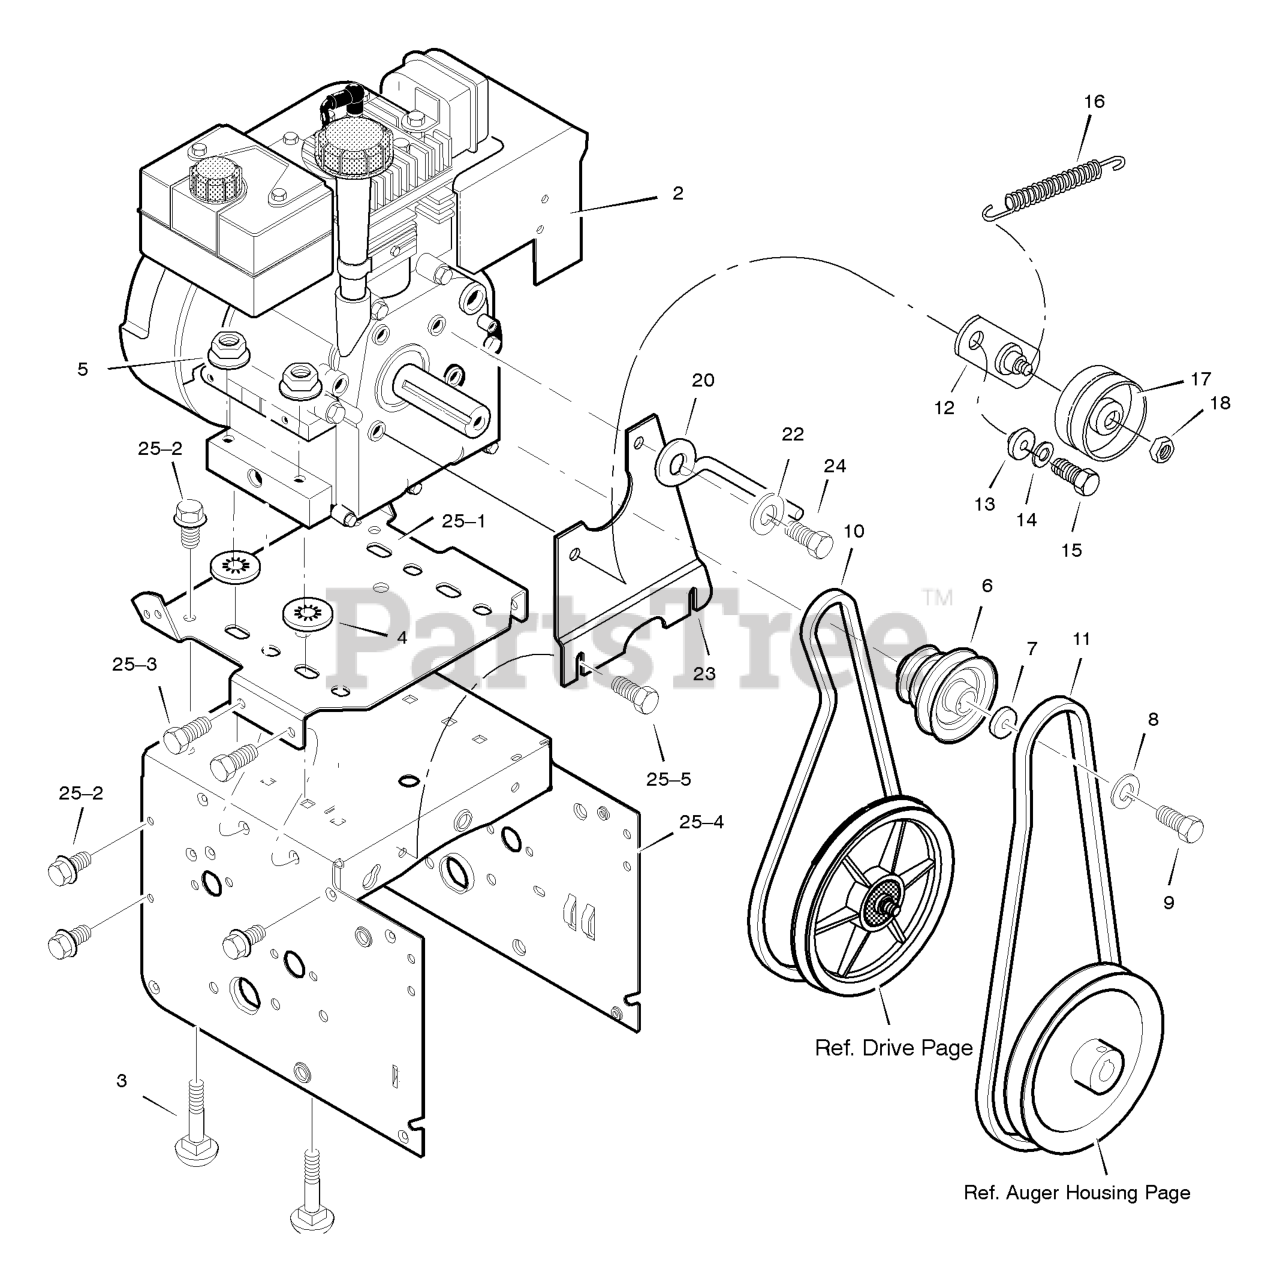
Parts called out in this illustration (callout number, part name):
2	ENGINE
3	BOLT, CARRIAGE 5/16-18
4	RETAINER, PUSH
5	NUT, HEX 5/16-18
6	PULLEY, ENGINE
7	WASHER
8	WASHER .38ID
9	SCREW, 3/8-24 x 1.00
10	BELT, DRIVE V 3L
11	BELT, AUGER V 4L
12	BRACKET ASSEMBLY, IDLER
13	BUSHING, IDLER BRACKET
14	WASHER, SPLIT
15	SCREW 5/16-24 X 1.00
16	SPRING, IDLER TRACTION DRIVE
17	PULLEY, IDLER
18	NUT, JAM 3/8-16
20	GUIDE, BELT
22	WASHER, SPTLK .31X.58X.08
23	PLATE, ANTI VIBRATION
24	SCREW, 5/16-24 x 1.00
25	FRAME ASSEMBLY
25-1	PLATE, ENGINE MOUNT
25-2	SCREW, TAP 1/4-20 X .63
25-3	SCREW, TAP 5/16-18 X .50
25-4	FRAME, MOTOR BOX
